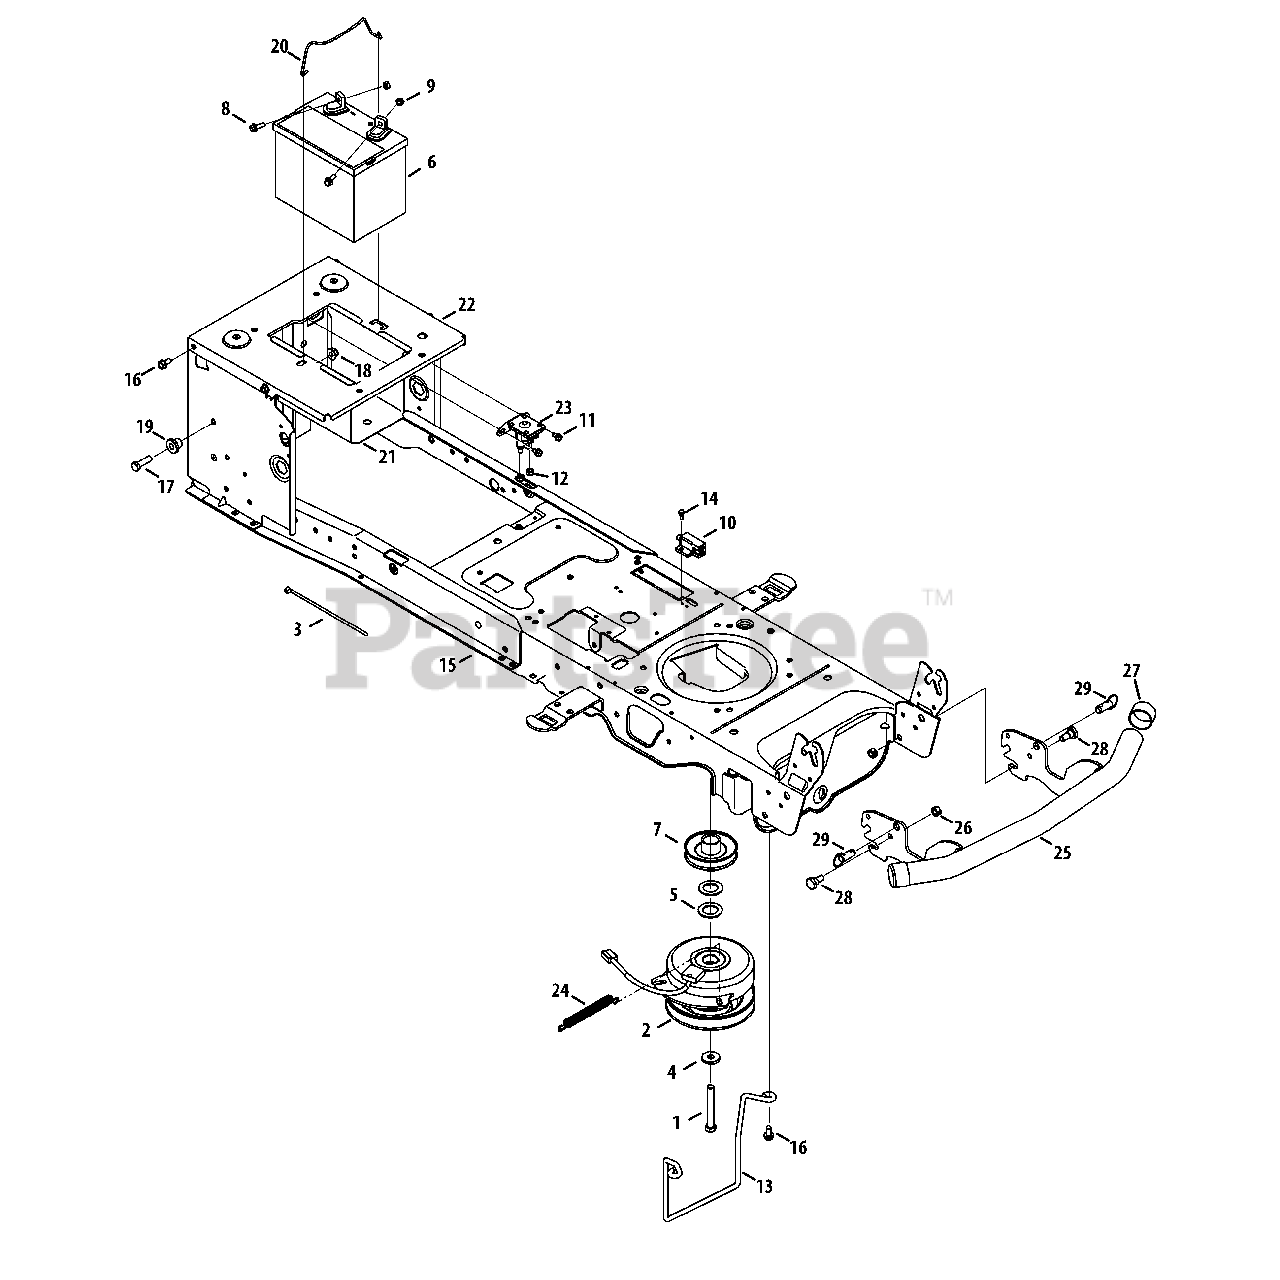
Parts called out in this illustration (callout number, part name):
1	Hex Screw, 7/16-20, 3.50, Gr5, Lock
2	Clutch, Electric PTO
2	Clutch Harness Wire 11.625"
3	Cable, Tie, 3/16 X .05 X 7.4
4	Washer, Flat, .450 x 1.25 x .164
5	Washer, Flat, 1.031 X1.620 X.095
7	Engine Pulley, Electric PTO
8	Hex Flange Screw, 1/4-20, .75, Gr5
9	Nut, Sems, 1/4-20
10	Switch, Interlock
11	Screw, Self-tapping, 1/4-20, 0.375
12	Nut, Flange Lock, 1/4-20, Nylon
13	Rod, Keeper
14	Screw, Shoulder, #10-32, .50
15	Frame Assembly, Lower
16	Screw, Self-tapping, 5/16-18, .750
17	Hex Screw, 3/8-16, 1.25, Gr5
18	Nut, Flange Lock, 3/8-16, Nylon
19	Spacer, Shoulder, .38 X 1.0 X .70
20	Rod, Battery
21	Tray, Battery
22	Bracket, Frame, Seat
23	Solenoid, 12V, 100 Amp, 4 term
24	Spr, Extn, .38 Dia X 3.25
25	Bumper Assembly, Universal
26	Hex Lock Nut, 3/8-16
27	Cap, Bumper
28	Bolt, Shoulder, .496 x .336, 3/8-16
29	Pin, Quick Release, 1/2 Dia x .50
